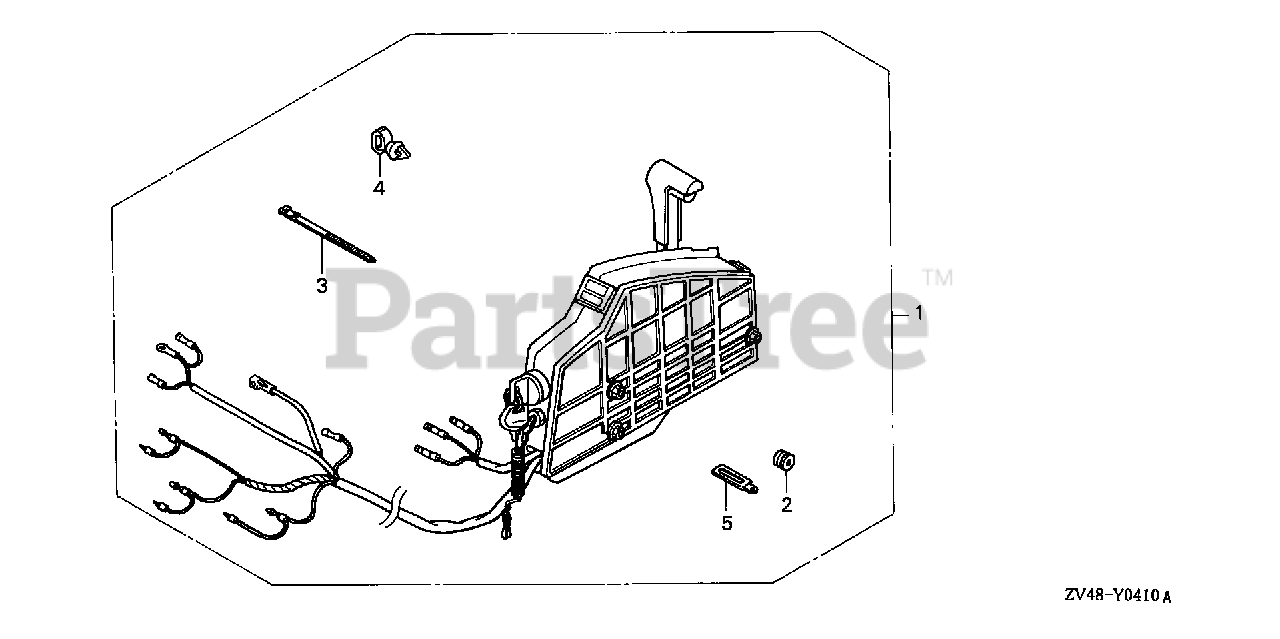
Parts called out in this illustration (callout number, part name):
1	BOX SET, CONTROL
2	RUBBER, TANK MOUNTING
3	BAND, WIRE
4	CLIP, WIRE HARNESS (25MM)
5	CLIP B, CORD
